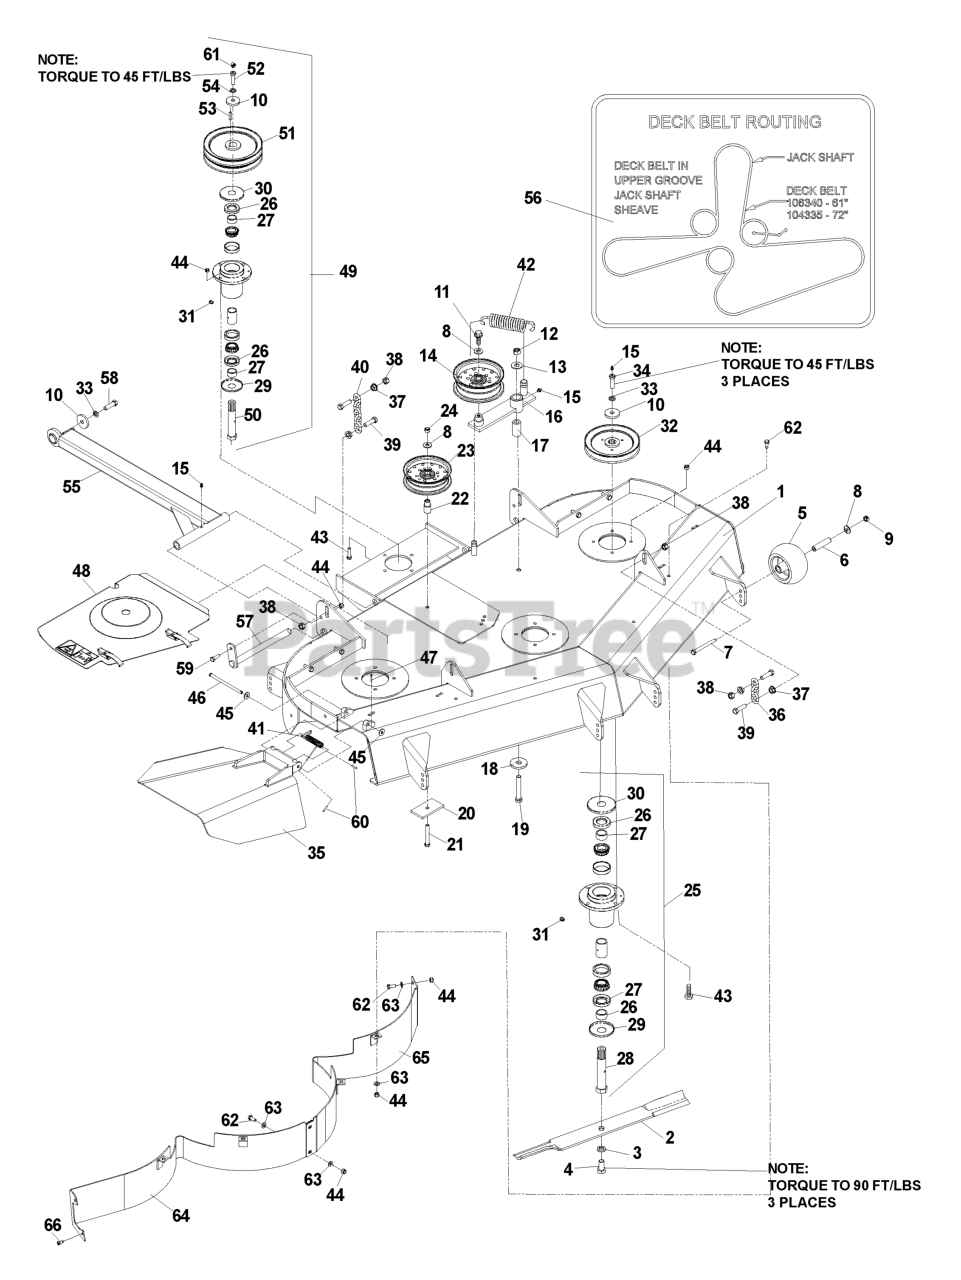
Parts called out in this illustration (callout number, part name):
1	DECK W/DECALS 61" TUNNEL HUS
2	BLADE OEM 21" (61" DECK)
3	LOCKWASHER 5/8
4	HCS 5/8F X 1 1/4
5	ANTI-SCALP ROLLER
7	HCS 3/8C X 3 1/2
8	WASHER 3/8 FLAT
9	NUT 3/8C CENTERBLOCK
10	SPINDLE WASHER
11	4CS 3/8C X 1 SERRATED HEAD
12	NUT 1/2-13 HEX NYLOC ZD
13	WASHER 1/2 FLAT
14	IDLER PULLEY
15	ZERK
17	PIVOT BUSHING
18	WASHER, SUPPORT
19	HCS 1/2C X 3 1/4
20	SUPPORT PLATE
21	SCREW 3/8C X 2 3/4 HEX CAP
22	IDLER BUSHING
23	IDLER PULLEY
24	NUT 3/8-16 NYLOC
25	SPINDLE ASSY - 52/61"
26	SHAFT SEAL
28	52/61 SPINDLE - SPLINED SHAFT
29	BOTTOM DUST CAP
30	TOP DUST CAP
31	PLUG-VENTED
32	RP PULLEY - 61"
33	WASHER 7/16 LOCK
34	DRILLED BOLT 7/16-20 X 1 1/2"
35	DISCHARGE CHUTE 61"
36	LIFT CHAIN - 3 LINK
37	NUT 7/16C WHIZ
38	NUT 7/16C CENTERLOCK
39	HCS 7/16C X 1 1/2
40	LIFT CHAIN
41	SPRING - TORSION
42	DECK SPRING
43	HCS 5/16C X 1 1/4
44	NUT 5/16 NYLOC
45	WASHER 5/16 FLAT
46	PIN-CLEVIS 5/16 DIA X 5.19 ZD
47	RP_COTTER PIN 1/8 X 3/4
48	61 BELT SHIELD ASM - RH
49	JACKSHAFT ASSY LOWER
50	JACKSHAFT SPINDLE
51	SHEAVE WSL
52	DRILLED BOLT 7/16-20 X 1 1/2"
53	KEY 1/4 SQ X 1 1/8
54	WASHER 7/16 LOCK
55	STRUT WELDMT, L.H.
56	BELT, DECK
58	HCS 7/16F X 1 1/2
59	HCS 5/16C X 1
60	CAP-SLEEVE
62	HCS 5/16C X 3/4
63	FLAT WASHER 5/16 SAE
64	61 FRONT BAFFLE WELDMT - R.H.
65	61 FRONT BAFFLE WELDMT - L.H.
66	HEX CAP SCREW 1/4
